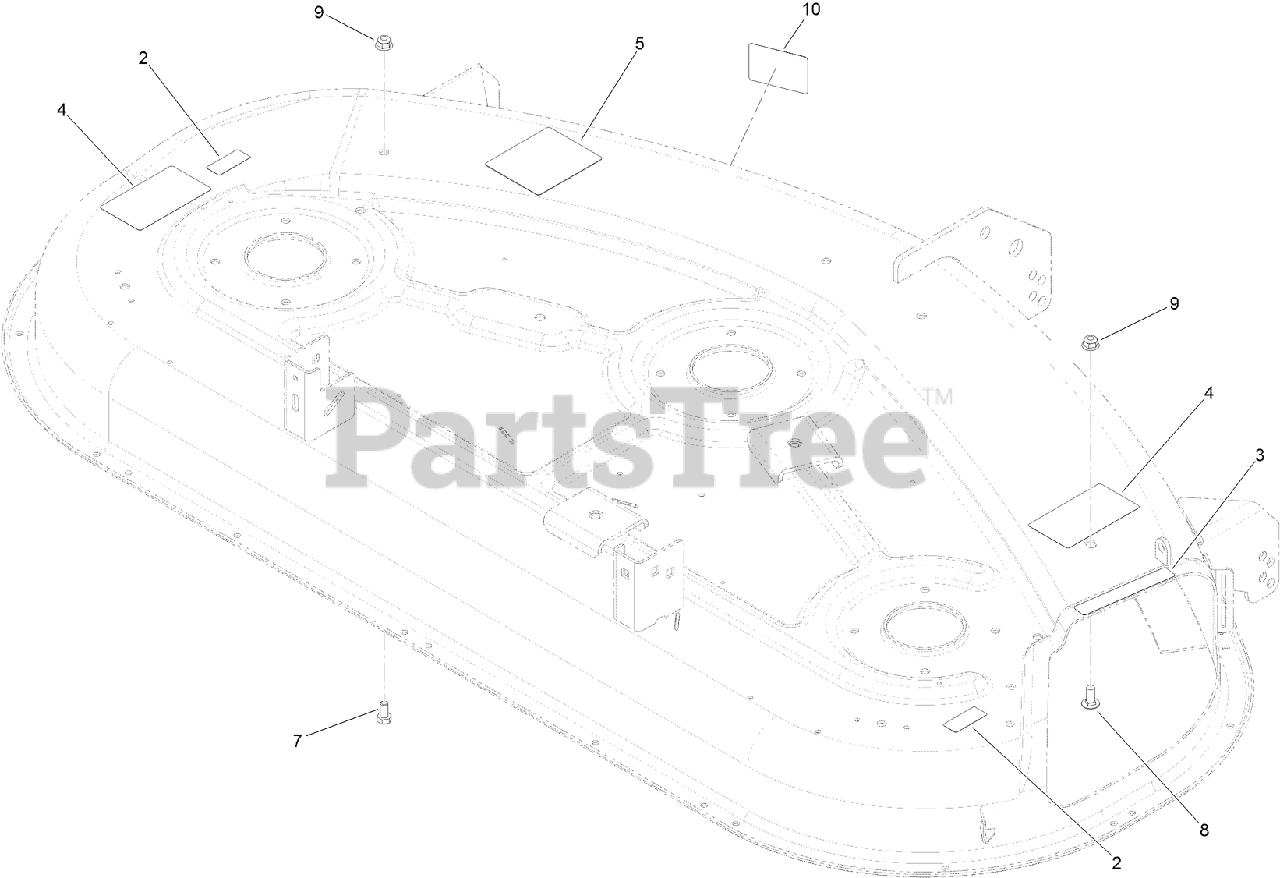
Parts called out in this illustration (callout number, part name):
2	DECAL-DANGER
3	DECAL-DANGER
4	DECAL-DANGER
5	DECAL-ROUTING, BELT
7	SCREW-HH
8	SCREW-CARR
9	NUT-HF, NI
10	DECAL-SCALP, ANTI
